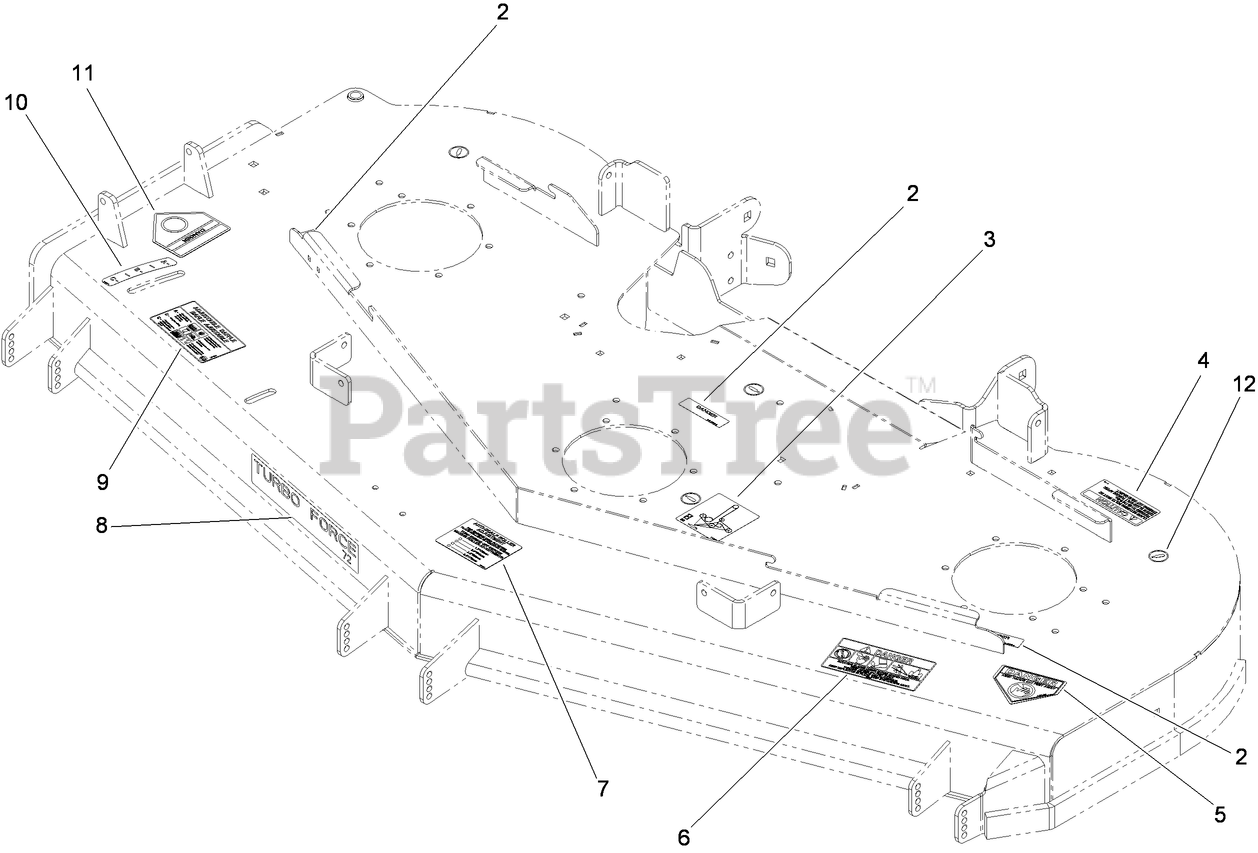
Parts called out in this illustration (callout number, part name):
2	DECAL-COVER, MISSING
3	DECAL-ROUTING, DECK BELT
4	DECAL-TORQUE
5	DECAL-DANGER
6	DECAL-DANGER, THROWN OBJECT
7	DECAL-SCALP, ANTI
9	DECAL-ADJUSTMENT, BAFFLE
10	DECAL-SETTING, BAFFLE
11	DECAL-DANGER
12	DECAL-GREASE
